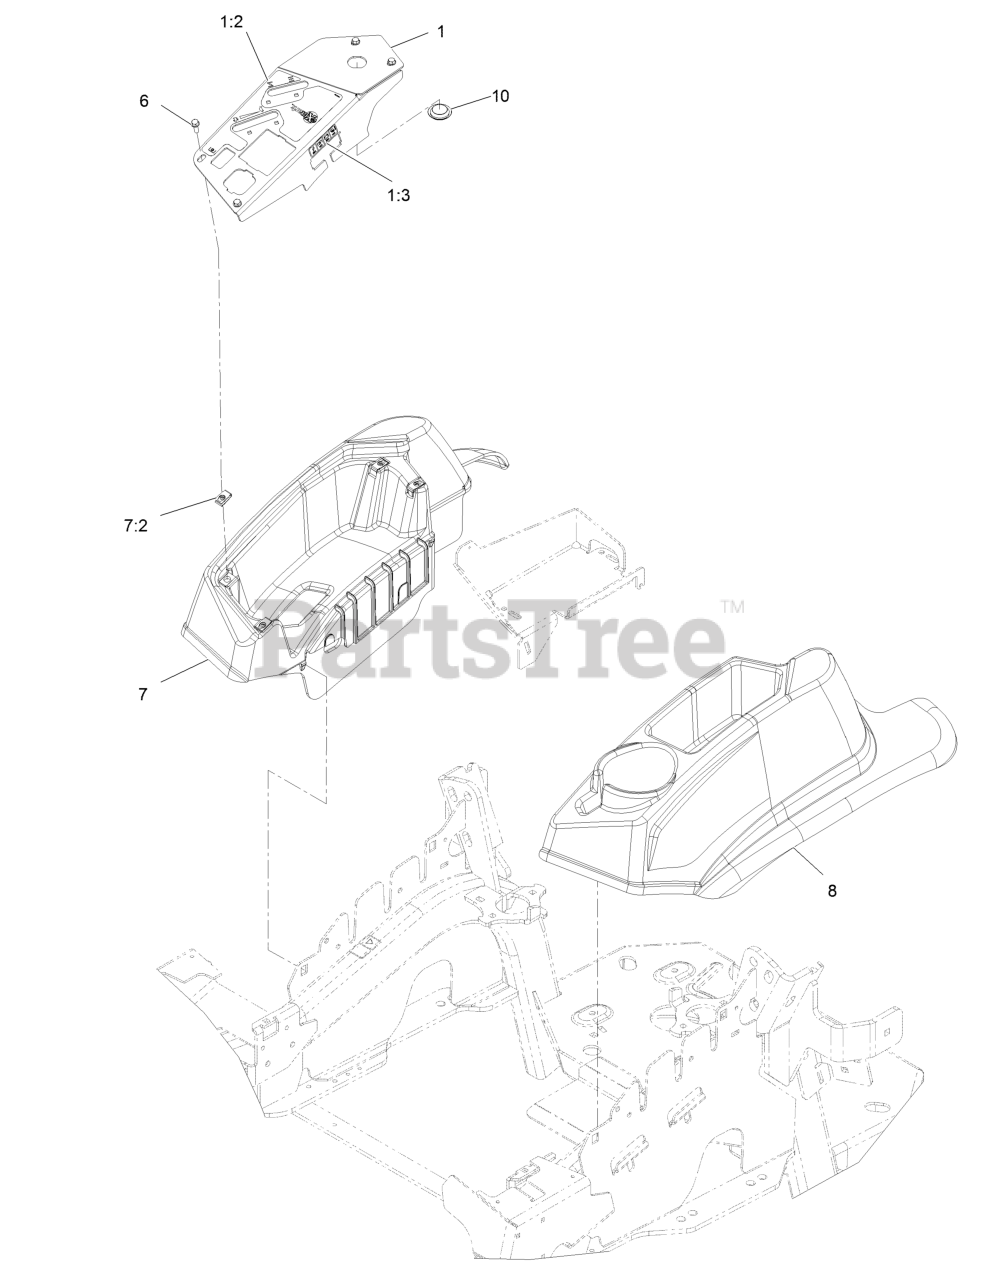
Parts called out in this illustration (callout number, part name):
1	Console,Panel W/Decal
1:2	Decal-Control Panel Non-Efi
1:3	Decal-Fuses
6	Screw-Machine 1/4-20 X 3/4
7	Console,RH As ASM
7:2	Nut-Retainer-Panel 1/4-20
8	Console, LH As
10	Plug-Plastic
